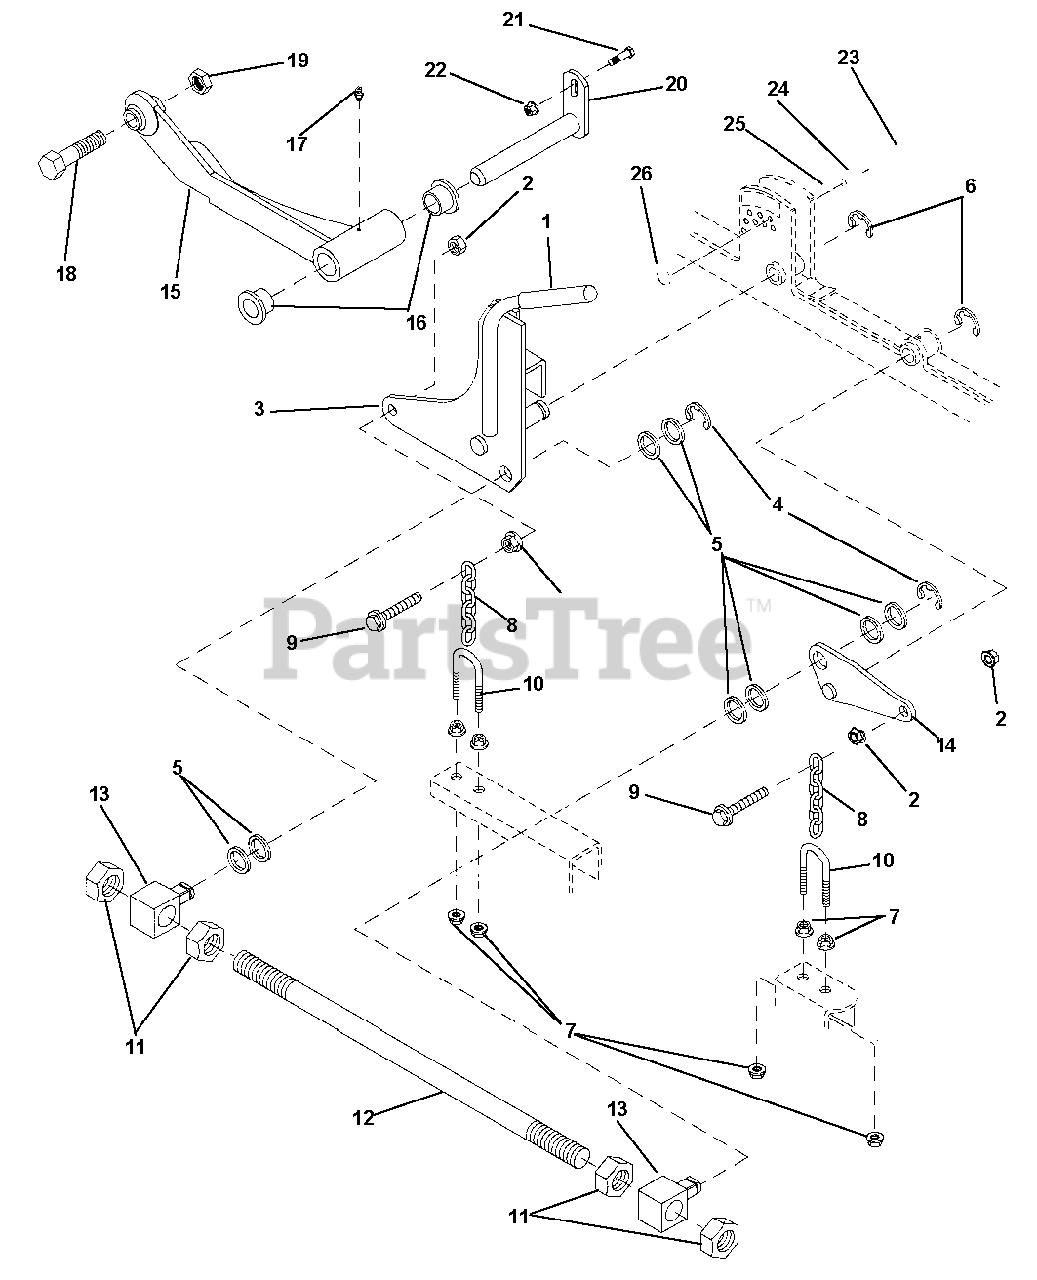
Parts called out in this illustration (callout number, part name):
1	Grip, Control Lever
2	Locknut, M10 x 1.50 WHIZ GR10
3	Weldment, LH Rear Lift Arm
4	Ring, Retaining
5	Washer, JDS24 .891 x 1.375 x .048-S
6	Ring, Retainer (E Series)
7	Nut, Flange .375-16
8	Chain, 6 Links
9	Screw, Hex, Flat, JDS121, M10 x 1.5 x 40
11	Nut, Hex .75
12	Rod, Deck Lift Assembly
13	Swivel, Deck Lift
14	Lift Arm Weldment, LH Front
15	Thrust Arm, LH (994109)
16	Bearing, Flanged
17	Fitting, Lubrication
18	Bolt, Hex .75-10 x 3.00
19	Crown Locknut, .75-16 GR8
20	Pin, Welded
21	Bolt, Round Head Square Neck M8-1.25 x 25 8.8
22	Nut, Lock, Flange M8-1.25
23	Pin, Clevis .468 x 4.16 x 3.89
24	Bushing, H.O.C. Pin Assembly
25	Push Nut Retainer, M12 x 21.5
26	Ring, Locking
